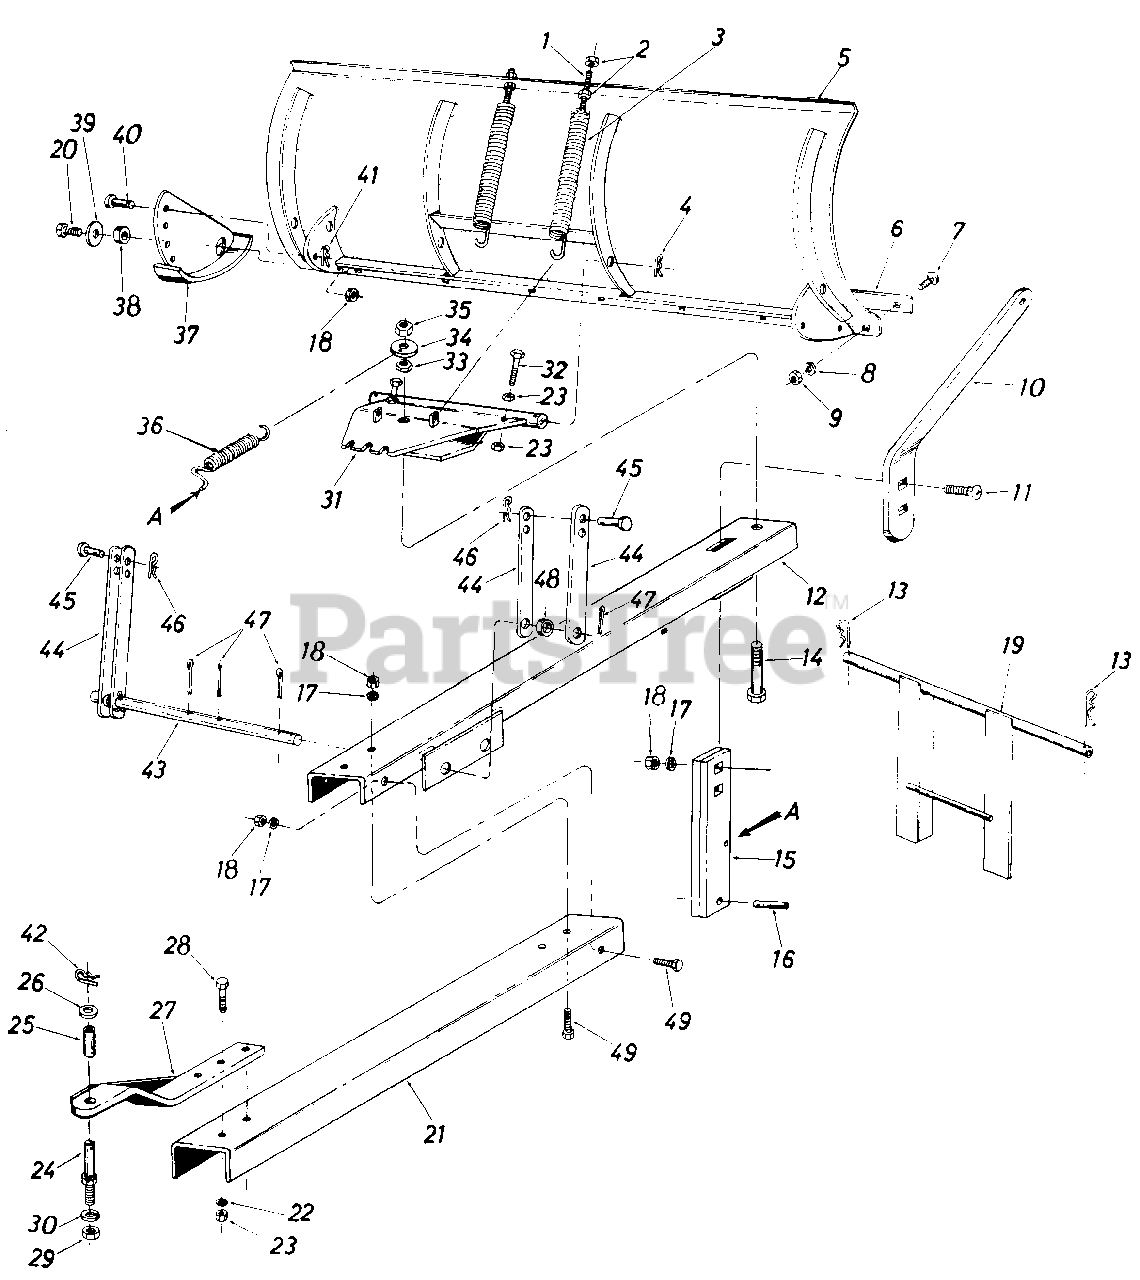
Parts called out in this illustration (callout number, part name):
1	Hex Scr. 3/8-16 x 4.50" Lg.
2	Hex Nut 3/8-16 Thd.
3	Blade Adjustment Spring
4	Hair Pin Cotter, 5/32
5	54" Blade Ass'y.
6	Wear Plate
7	Carriage Bolt 5/16-18 x .75" Lg.
8	L.-Wash. 5/16" Scr.
9	Hex Nut 5/16-18 Thd.
10	Lock Extension Bar
11	Carriage Bolt 3/8-16 x 1.25" Lg.
12	Front Push Bar Ass'y.
13	Hair Pin Cotter, 5/32
14	Hex Scr. 3/4-10 x 3.50" Lg.
15	Angle - Lock Bar
16	Spring Pin Spiral .25" Dia. x 1.00" Lg.
17	L.-Wash. 3/8" Scr.
18	Hex L.-Nut 3/8-16 Thd.
19	Guide Bracket Ass'y.
20	Hex Scr. 3/8-16 x .75" Lg.
21	Rear Push Bar Channel
22	L-Wash. 1/2" Scr.
23	Hex Nut 1/2-13 Thd.
24	Link Clevis Pin
25	Spacer 1" O.D. x 21/32" I.D. x .75" Lg.
26	Fl-Wash. 21/32 I.D. x .090 O.D.
29	Hex Jam L.-Nut 5/8-18 Thd.
30	L.-Wash. 5/8" Scr.
31	Pivot Plate Ass'y.
32	Hex Scr. 1/2-13 x 2.00" Lg.
32	Skid Assembly
33	Hex Jam Nut 3/4-10 Thd.
34	Fl.-Wash. 3/8"
35	Hex Lock Nut 3/4-10 Thd.
36	Angle Lock Spring
38	Bushing, Pivot Skid
39	Fl.-Wash..385" I.D. x 1.00" O.D.
40	Clevis Pin 5/16" Dia. x 3/4" Lg.
41	Hair Pin Cotter 3/32"
42	Hair Pin Cotter 5/32
43	Lift Shaft
44	Lift Link
45	Clevis Pin 1/2" Dia. x 1.00" Lg.
46	Hair Pin Cotter 3/32"
47	Cotter Pin 1/8" Dia. x 1.50" Lg.
48	Spacer, Lift Link
49	Hex Scr. 3/8-16 x 1.00" Lg.
